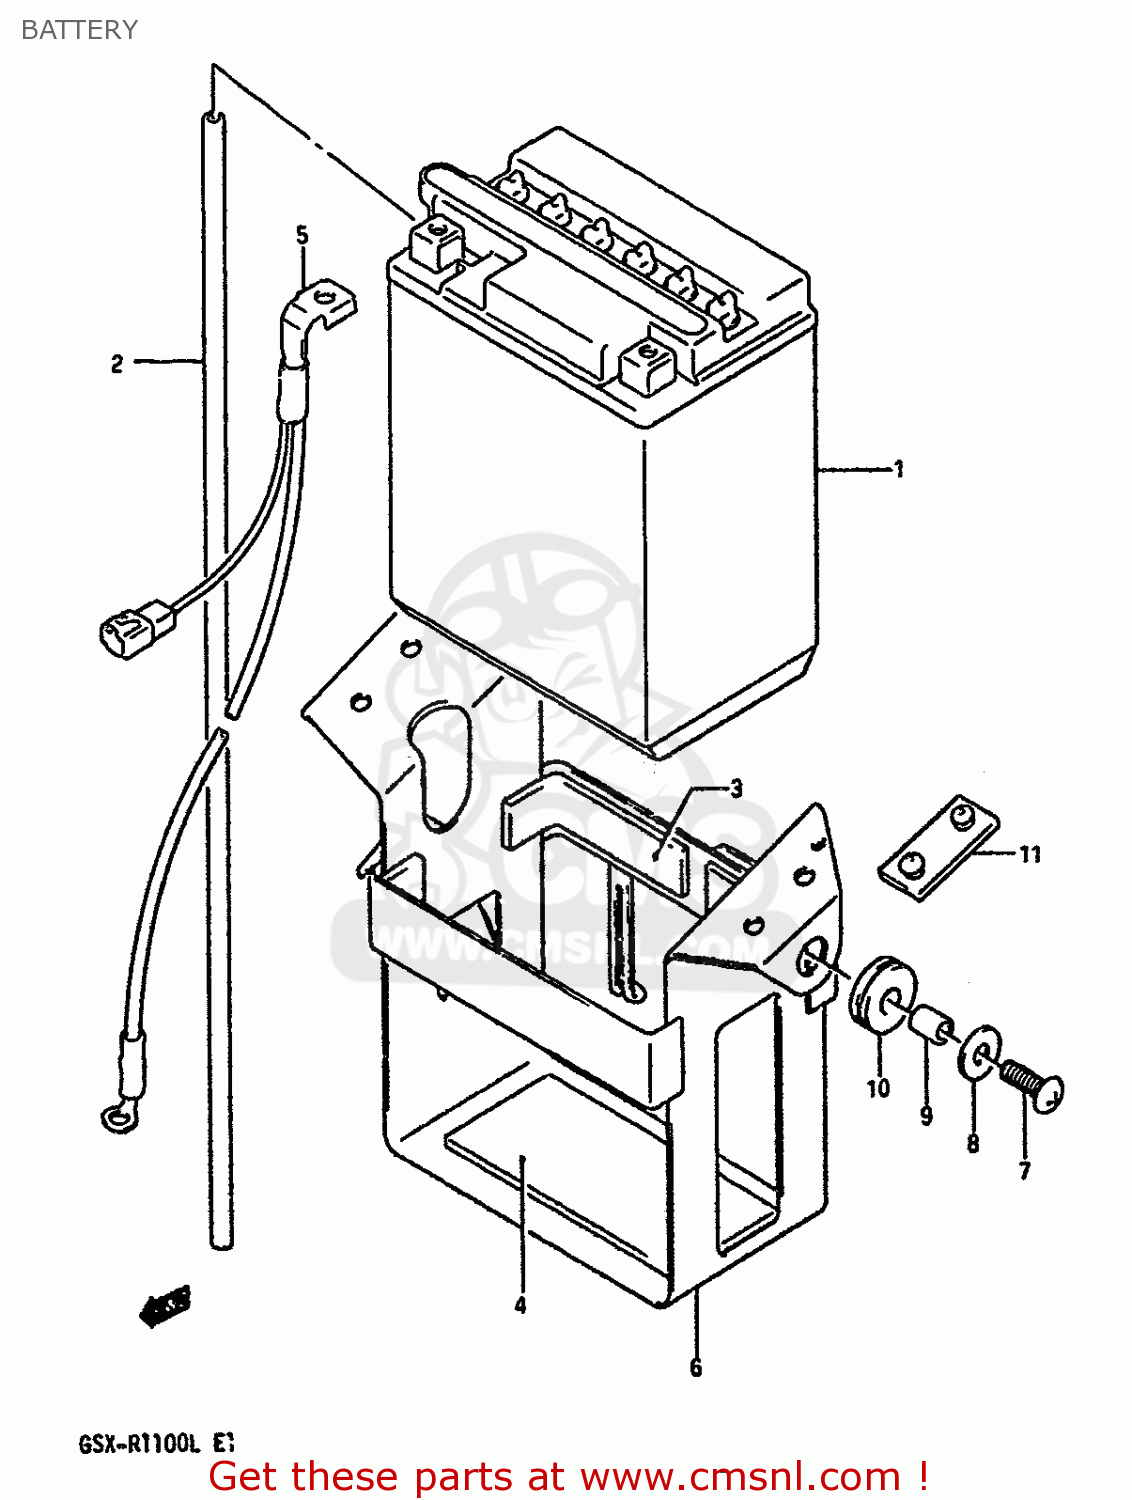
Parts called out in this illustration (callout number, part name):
1	BATTERY ASSY (12V)
2	HOSE,BATTERY EXHAUST
3	PROTECTOR,20X9
4	PROTECTOR(170X95X3.0)
5	WIRE,BATTERY MINUS LEAD
6	HOLDER,BATTERY
7	SCREW
8	WASHER
9	SPACER
10	CUSHION
11	CUSHION
